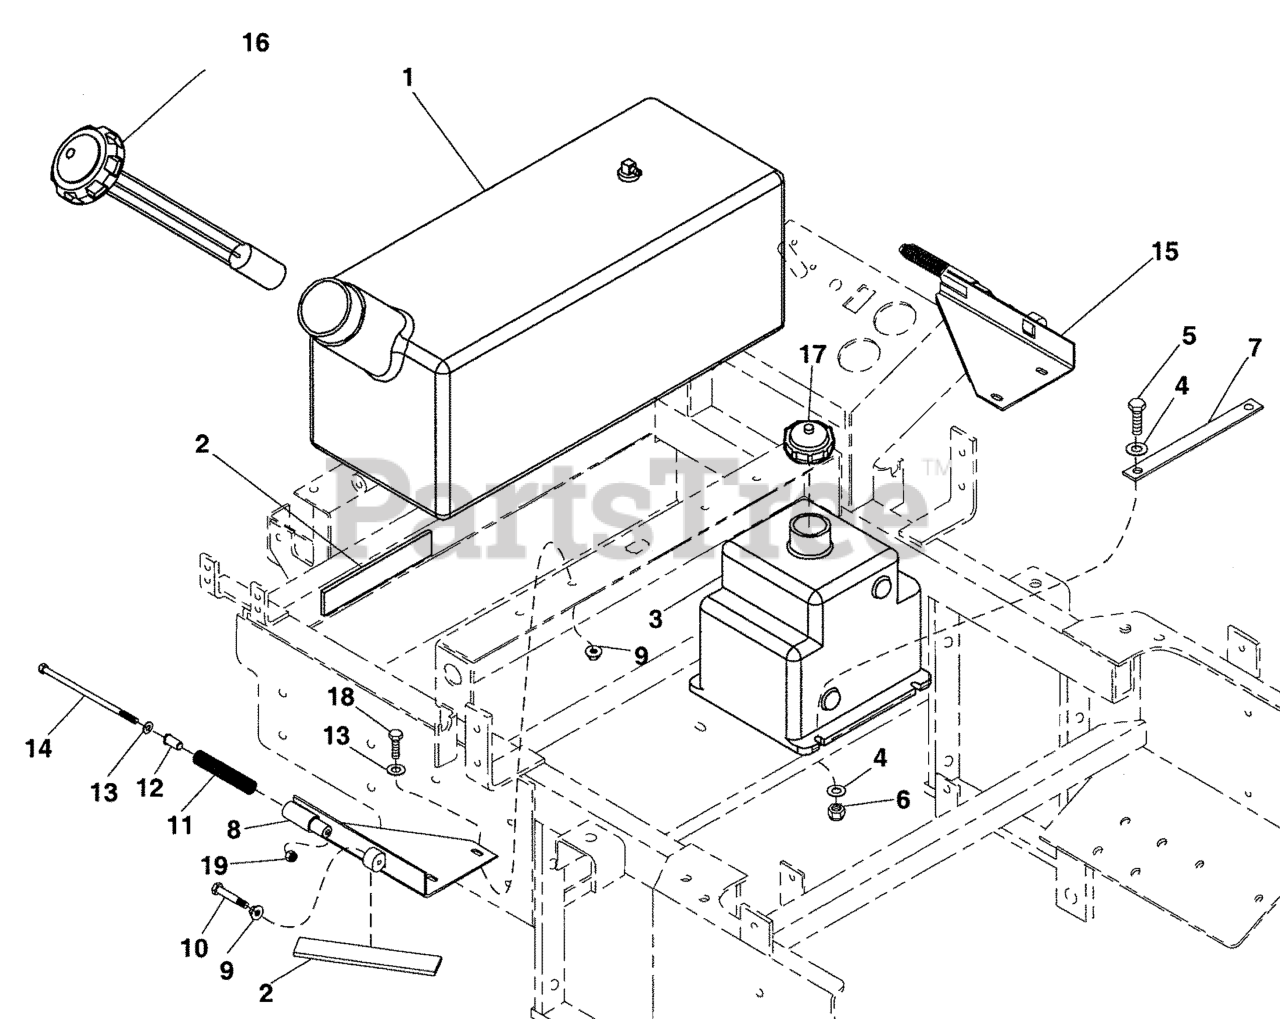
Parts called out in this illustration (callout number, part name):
1	FUEL TANK
2	RUBBER PAD
3	HYDRAULIC RESERVOIR
4	WASHER, 3/8 SAE
5	BOLT, 3/8-16 X 1-1/2" GD5 CZ
6	NUT, 3/8-16 HEX NYLON LOCK
7	HOLD DOWN PLATE
8	SPRING BRACKET, Left
9	NUT, 5/16-18 HEX SERRATED FLANGE (SMALL)
10	BOLT, 5/16-18 x 2-1/4
11	SPRING, Compression
12	BUSHING, Flange
13	WASHER, 5/16" SAE
14	BOLT, 5/16-18 x 7
15	SPRING BRACKET, Right
16	GAS CAP
17	CAP, Hydraulic Reservoir
18	BOLT, 5/16-18 X 3/4 GD5
19	NUT, Hex, Nylon Locking, 5/16-18
